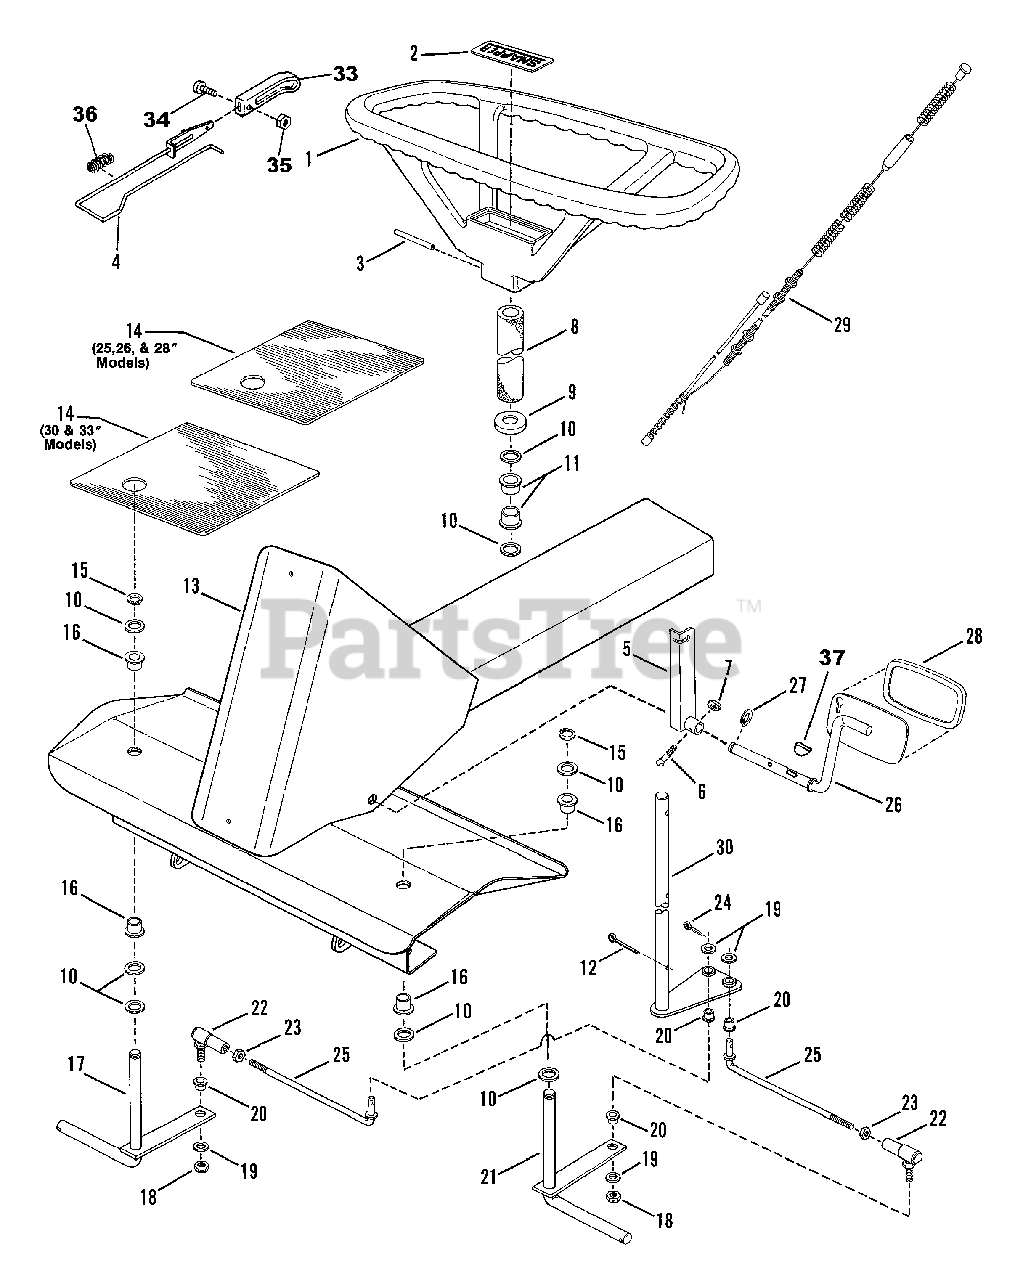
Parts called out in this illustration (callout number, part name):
1	ASS'Y, Steering Wheel
2	DECAL, Snapper
3	PIN, 1/4 x 1-1/2" Roll
4	BRACKET, Clutch/Brake
5	ARM, Clutch/Brake
6	BOLT, #10-32 x 1-3/8" Tapered
7	NUT, #10-32 Hex Lock
8	COVER, Steering Shaft (Foam)
9	COVER
10	WASHER, 3/4 Flat
11	BUSHING, 3/4" Steering Shaft
12	COTTER-PIN 3/16 x 1-1/2"
13	FRAME, Front (25, 26 & 28" Models)
14	PAD, Foot, Right Side Shown (25, 26 & 28" Models)
15	RING, Retaining 92)
16	BEARING
17	King Pin, R.H.
18	NUT, 3/8-24 Hex Lock
19	WASHER, 3/8" Flat
20	BUSHING
21	King Pin, L.H.
22	BALL JOINT, 3/8-24 Thread
23	NUT, 3/8-24 Hex
24	COTTER-PIN, 1/8 x 3/4"
25	TIE-ROD (30 & 33" Models)
26	PEDAL, Clutch/Brake
27	RING, Retaining
28	PAD, Clutch/Brake Pedal
29	CABLE, Clutch/Brake
30	SHAFT, Steering
33	KNOB
34	SCREW, #8-32 x 3/8" Rec. Filister Head
35	NUT, #8-32 Hex
36	SPRING
37	KEY, (#6) 5/32 x 5/8" Woodruff
